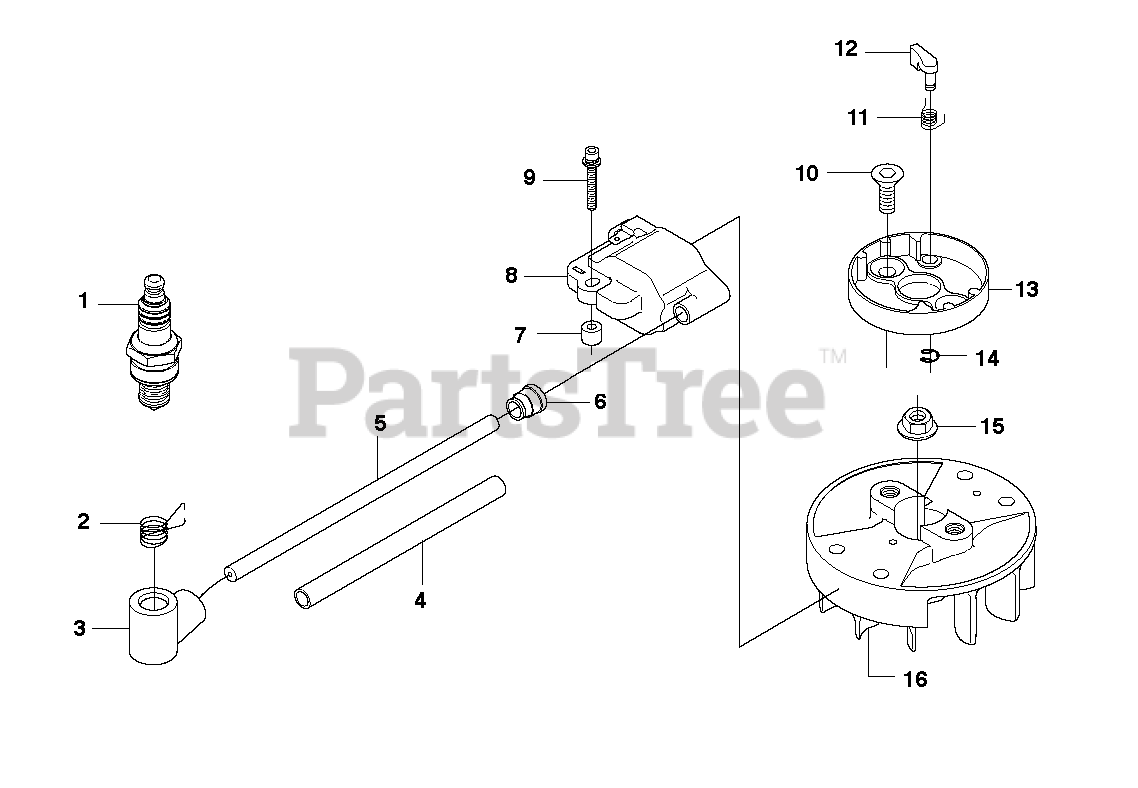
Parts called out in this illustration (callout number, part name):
1	SPARK PLUG NGK BPMR6Y
3	SPARK PLUG CONNECTION
8	IGNITION MODULE
11	RETURN SPRING
14	RETAINING RING
